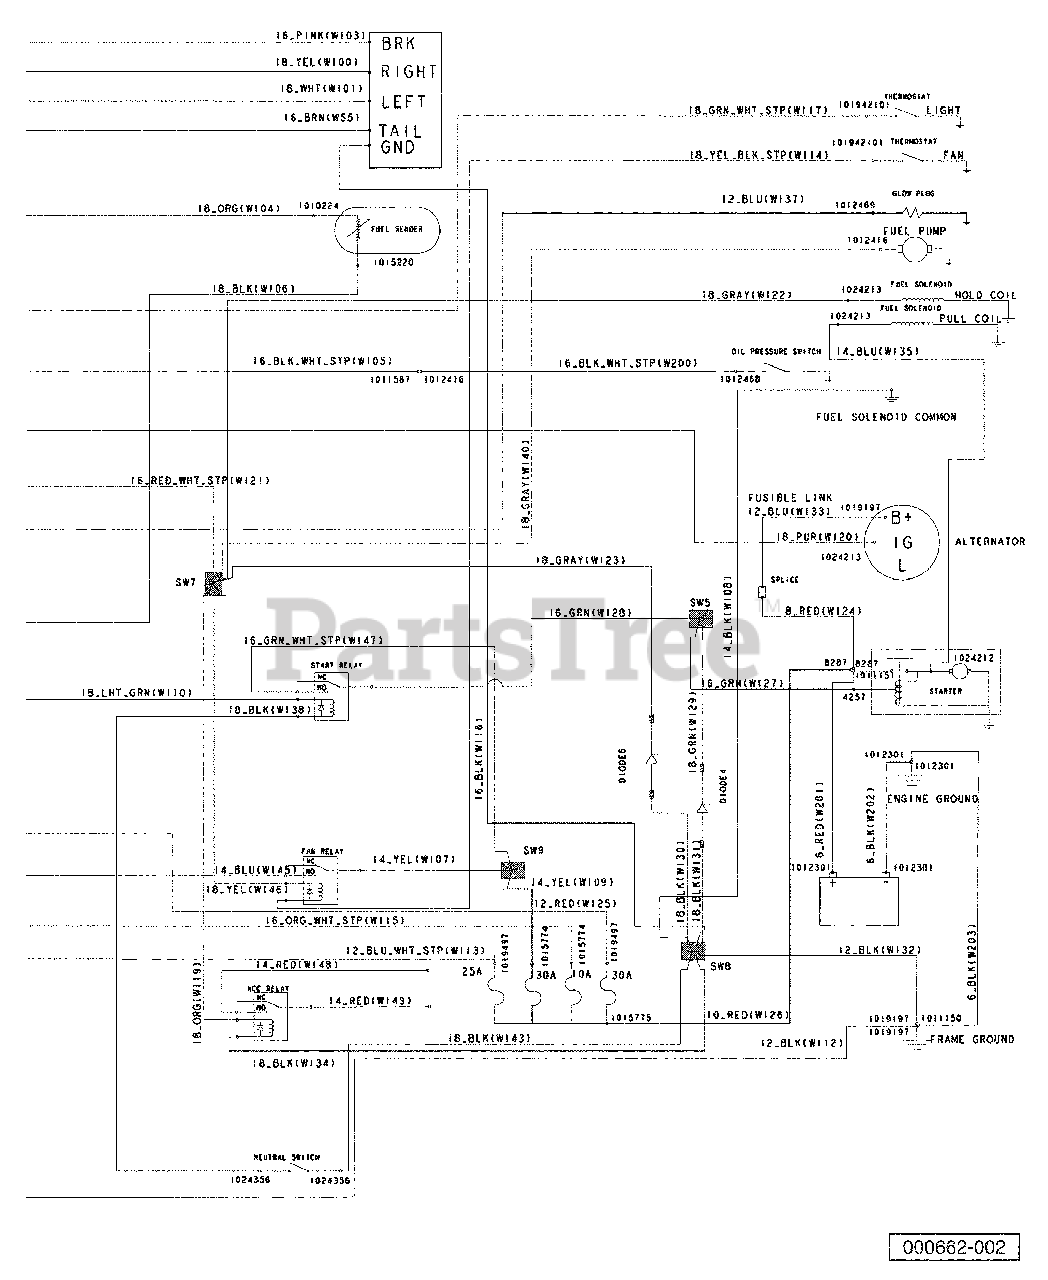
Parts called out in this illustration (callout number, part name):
1	Diode, General Purpose, 6.0a
2	Harness, Diesel AWD
3	Asm, Switch, Limit, Awd
